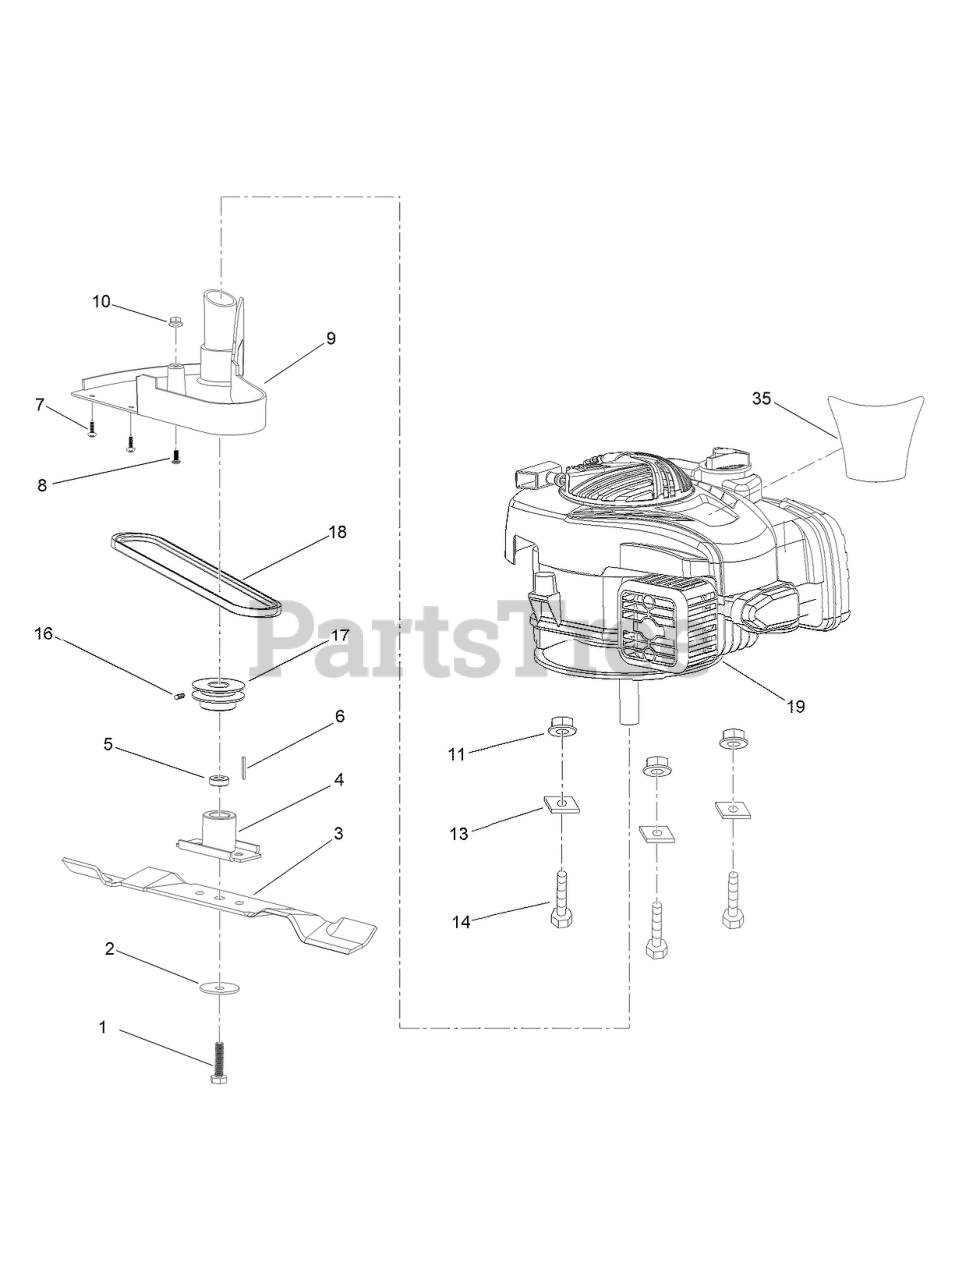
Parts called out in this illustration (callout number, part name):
1	BOLT-BLADE
2	WASHER-DISHED
3	BLADE-MULCH
4	SUPPORT-BLADE
5	SHEATH-BLADE
6	KEY-FLAT
7	SCREW-SELF DRIVING
8	SCREW-TOOTH
9	COVER-PULLEY, BELT
10	NUT-LOCK, FLANGE
11	NUT-LOCK, FLANGE
13	WASHER-SQUARE
14	BOLT-BLADE
16	SCREW-GRUB
17	PULLEY-DRIVE
18	BELT-TRIANGLE
19	ENGINE-BRIGGS STRATTON, 500E
35	DECAL-SHROUD
